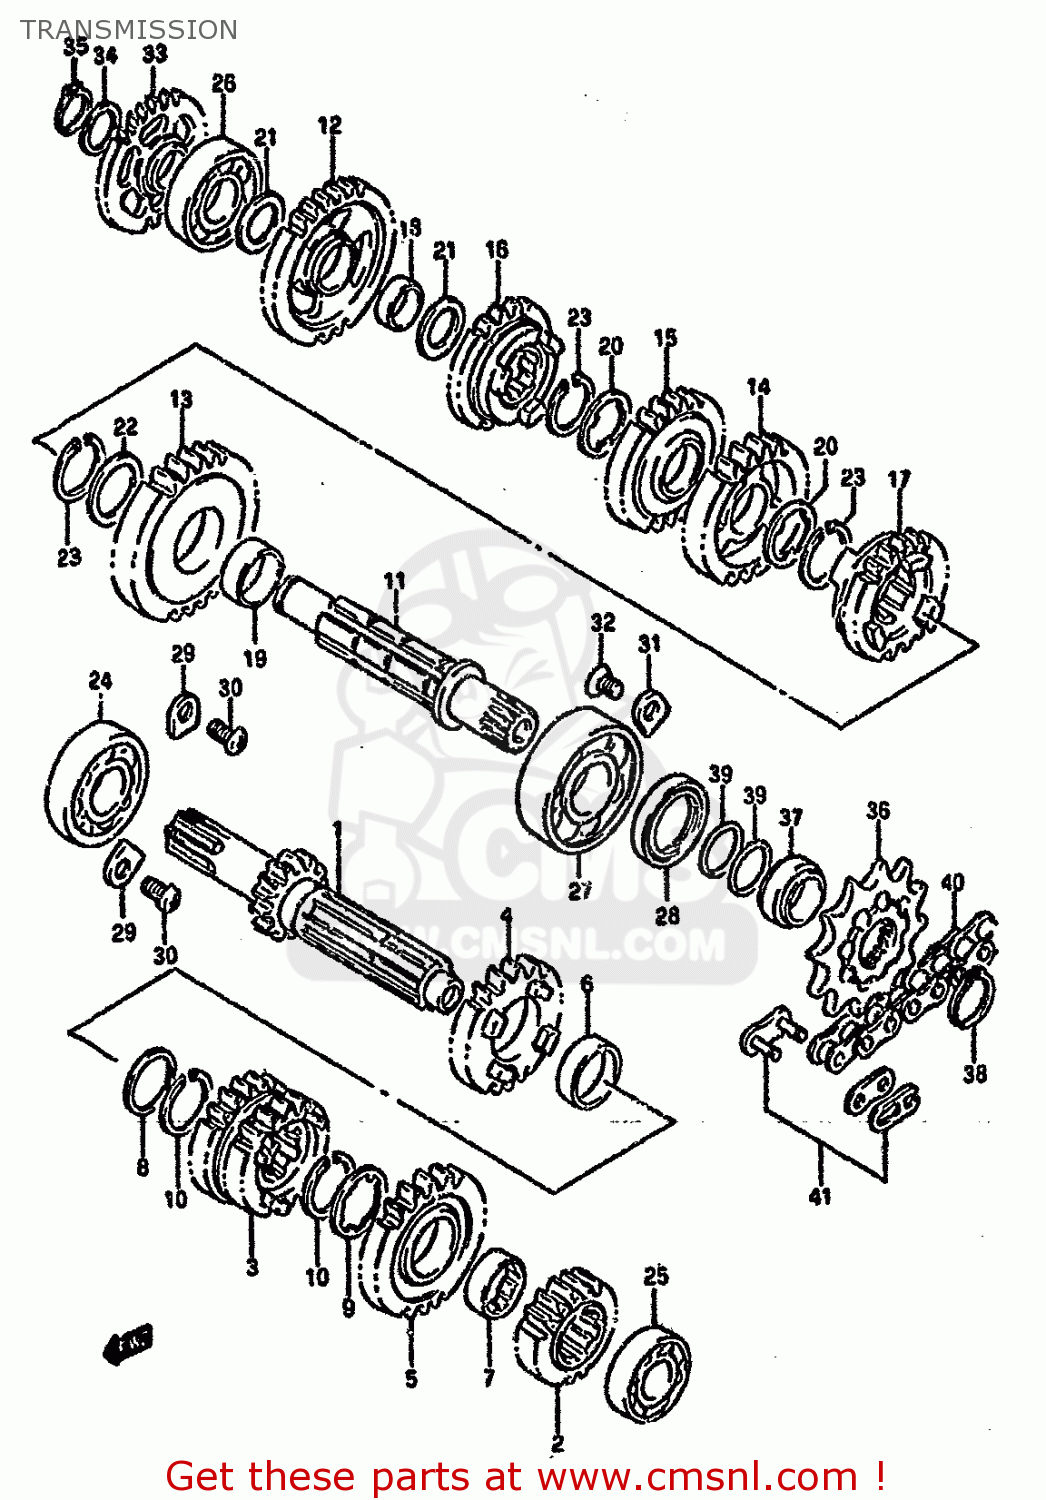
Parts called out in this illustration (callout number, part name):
1	SHAFT,COUNTER(NT:14)
2	GEAR,2ND DRIVE(NT:16)
3	GEAR,THIRD DRIVE
4	GEAR,FIFTH DRIVE (NT:19)
5	GEAR,SIXTH DRIVE (NT:20)
6	BUSHING
7	BUSH,6TH DRIVE GEAR
8	SHIM
9	WASHER,LOCK
10	CIRCLIP
11	SHAFT,DRIVE
12	GEAR,FIRST DRIVEN
13	GEAR,2ND DRIVEN(NT:28)
14	GEAR,THIRD DRIVEN
15	GEAR,FOURTH DRIVEN
16	GEAR,5TH DRIVEN(NT:20)
17	GEAR,SIXTH DRIVEN
18	BUSH(17X20X9)
19	BUSHING
20	WASHER
21	WASHER,THRUST
22	WASHER,THRUST
23	CIRCLIP
24	BEARING(20X47X12)
25	BEARING
26	BEARING(17X40X9.5)
27	BEARING(20X52X12.5)
28	SEAL,OIL(28X38X6)
29	RETAINER
30	SCREW
31	RETAINER,COUNTER BEARING,R
32	SCREW
33	GEAR,KICK STARTER IDLE
34	SHIM
35	CIRCLIP,17MM
36	SPROCKET,ENGINE
37	SPACER,ENGINE SPROCKET
38	CIRCLIP
39	O RING(D:1.9,ID:19.8)
40	CHAIN ASSEMBLY DID520DM.11
41	JOINT SET,CHAIN
